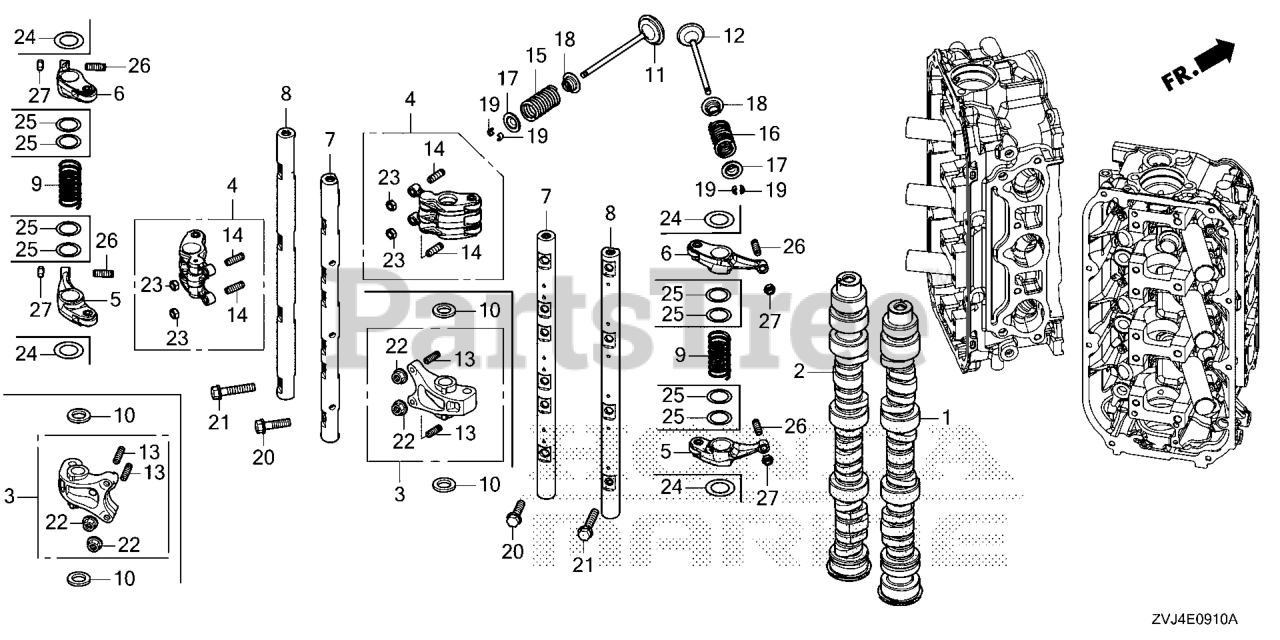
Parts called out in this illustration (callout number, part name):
1	CAMSHAFT, R.
2	CAMSHAFT, L.
4	ARM ASSY., IN. ROCKER
5	ARM COMP
6	ARM COMP
7	SHAFT, IN. ROCKER ARM
8	SHAFT COMP
9	SPRING, ROCKER ARM
9	SPG, RKR ARM
11	VALVE, IN.
12	VALVE, EX.
14	SCREW, TAPPET ADJUSTING
15	SPRING, VALVE (PINK) (NIPPON HATSUJO)
16	SPRING, EX. VALVE (YEL/GRN) (ASSOCIATE)
17	RETAINER, VALVE SPRING
18	SEAT, VALVE SPRING
19	COTTER, VALVE (FUJI VALVE)
20	BOLT, FLANGE (8X30)
21	BOLT, FLANGE (8X40)
23	NUT, TAPPET ADJUSTING
24	WASHER, THRUST
25	WASHER (25MM)
26	SCREW, TAPPET ADJUSTING
26	SCREW, TAPPET ADJG
27	NUT, TAPPET ADJUSTING (TOKAI TRW)
27	NUT, TAPPET ADJUSTING
